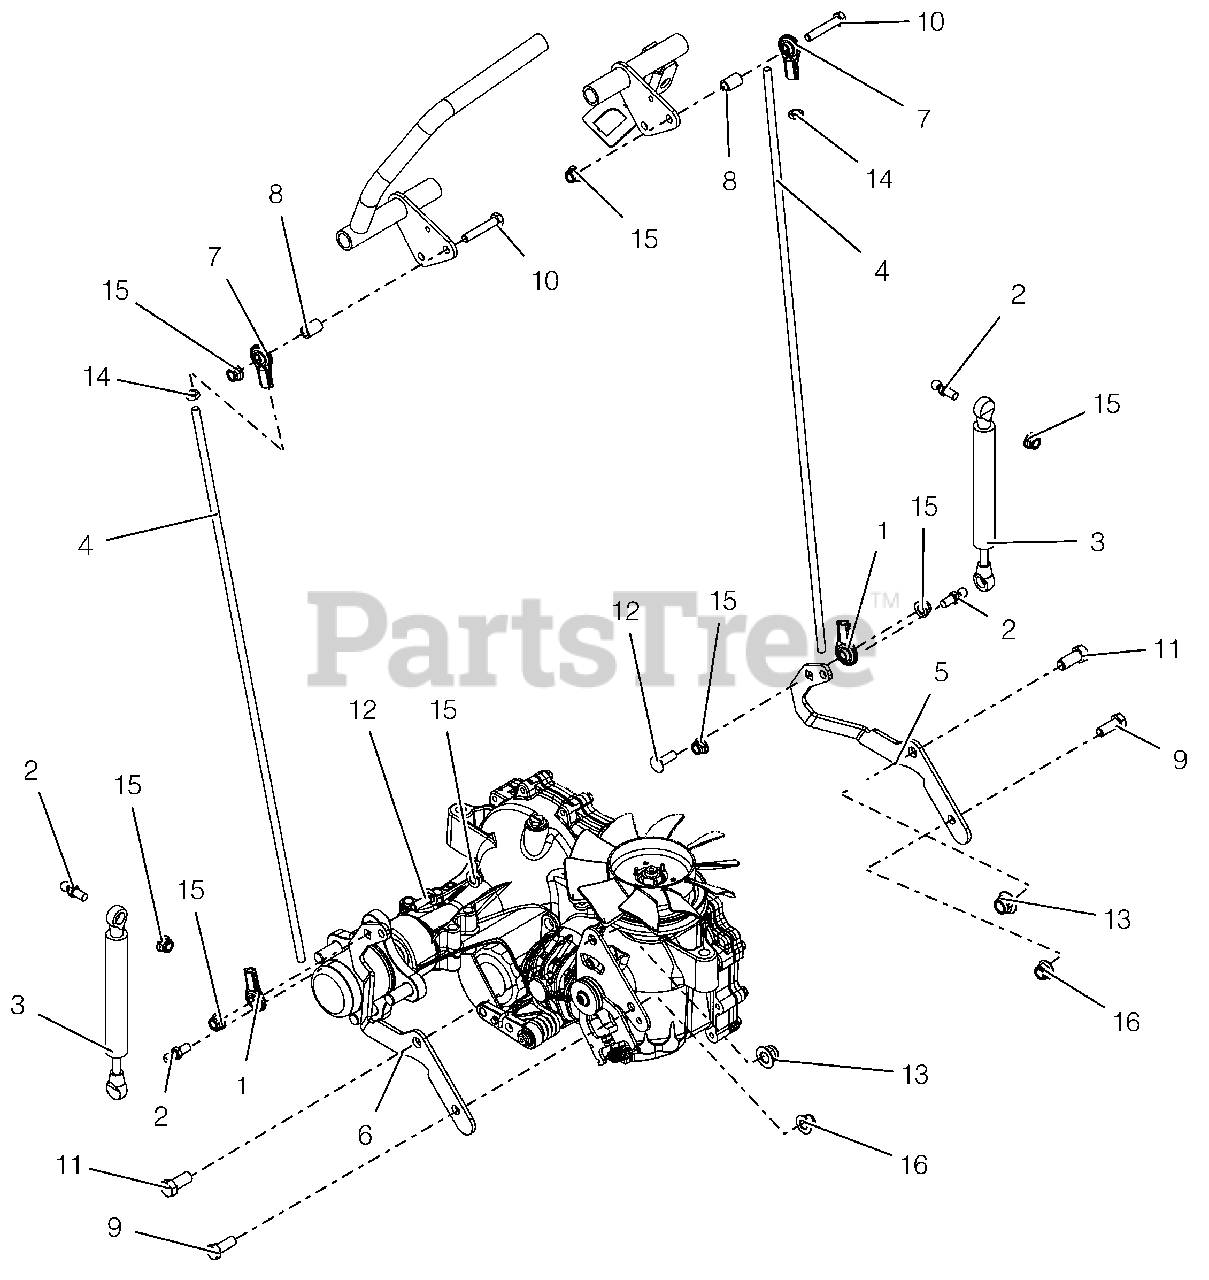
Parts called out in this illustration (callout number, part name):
1	ALIGNABALL, 5/16 RH THREAD
2	STUD- BALL
3	DAMPER, CONTROL
4	ROD, STEERING
5	BRKT, LH TRANS CONTROL
6	BRKT, RH TRANS CONTROL
7	ALIGNABALL, 5/16 LH THREAD
8	BSHG-SLV .328X.50X.75
9	@BLT-HEX .38-16X1.00 GR5 YWZC
10	@BLT-HEX .31-18X1.75 GR5 YWZC
11	@BLT-HEX .44-14X1.00 GR5 YWZC
12	@BLT-RDHDSQNK .31-18X1.00 G5YZ
13	@NUT-LK-NYL-FLG .44-14 YWZC
14	NUT-JAM LH .31-24 YWZC
15	@NUT-LK-NYL-FLG .31-18 YWZC
16	@NUT-LK-NYL-FLG .38-16 YWZC
